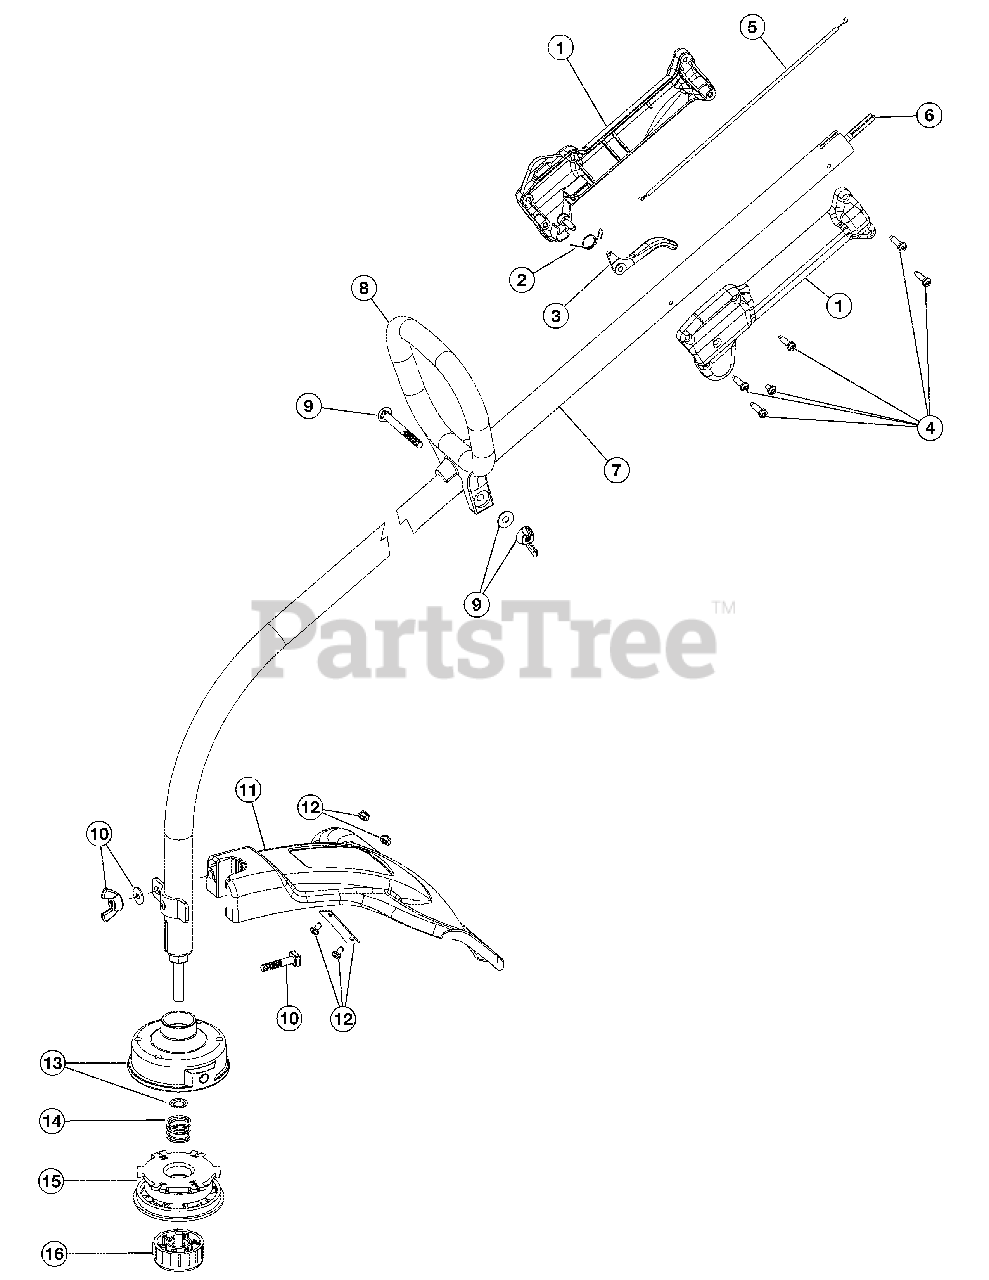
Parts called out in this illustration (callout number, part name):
1	Throttle Housing Assembly
2	Throttle Trigger Spring
3	Throttle Trigger
4	Throttle Housing Screws
5	Throttle Cable
6	Flexible Drive Shaft
7	Drive Shaft Housing
8	D-Handle Assembly
9	D-Handle Hardware
10	Guard Mounting Hardware
11	Guard Assembly
12	Blade Assembly
13	Outer Reel w/ Retainer
15	Inner Reel
16	Bump Knob
